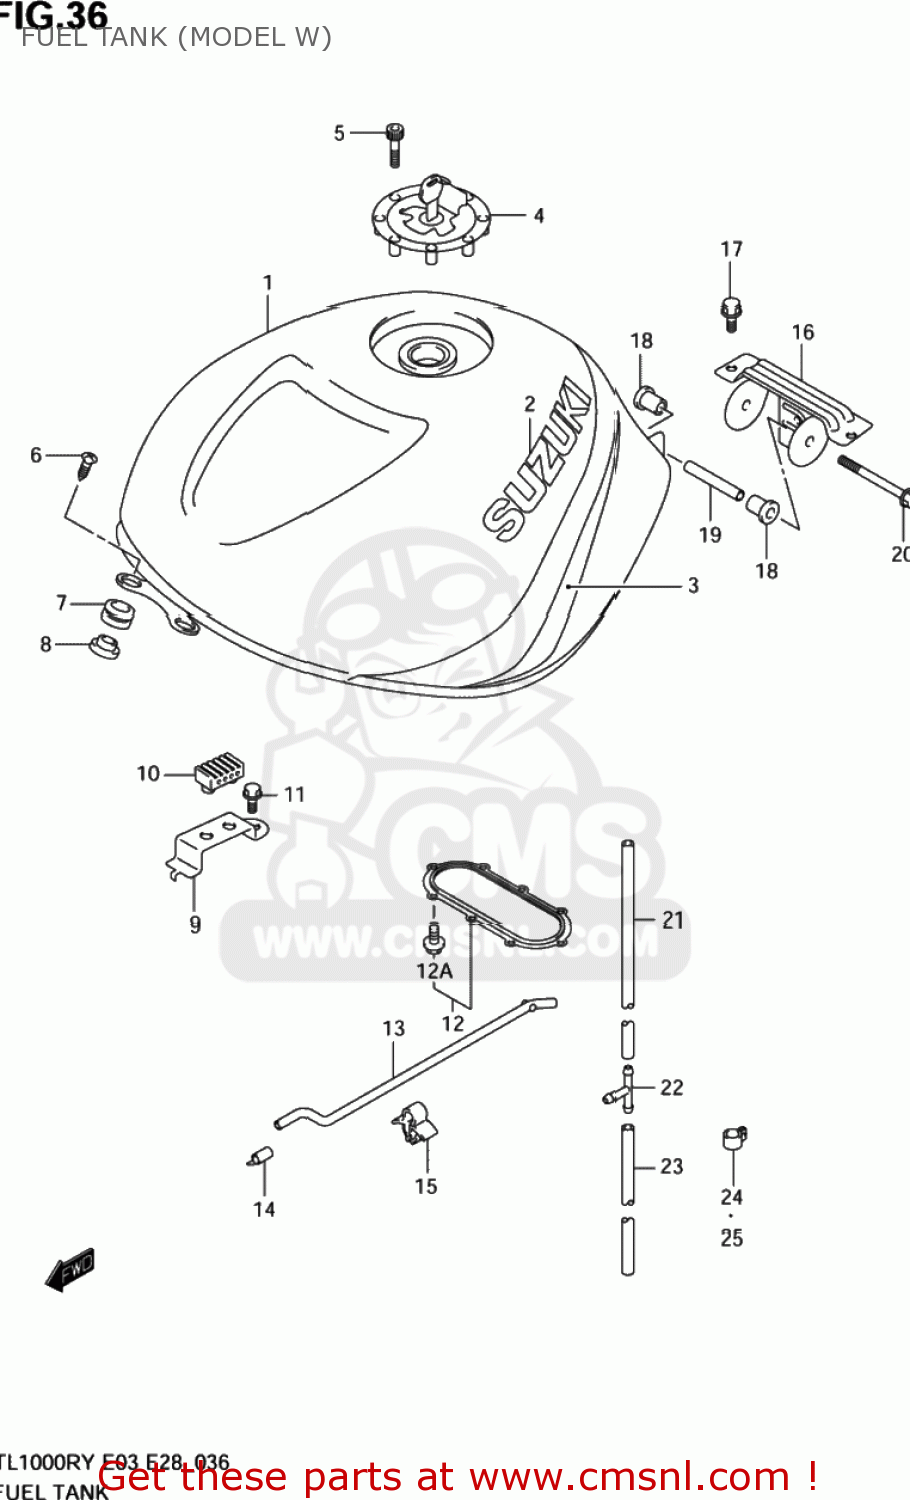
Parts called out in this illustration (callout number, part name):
1	TANK ASSEMBLY,FUEL
2	EMBLEM,FUEL TANK
3	TAPE SET,FUEL TANK(BLUE)
4	CAP SET,FUEL TANK
5	BOLT(5X20)
6	SCREW(6X25)
7	CUSHION
8	WASHER
9	BRACKET,FUEL TANK SIDE CUSHION
10	CUSHION,SEAT(40X20X15)
11	BOLT
12	PACKING SET,FUEL PUMP (NAS)
12A	BOLT,FUEL PUMP
13	STAY,FUEL TANK
14	CAP,OD:11
15	CLAMP
16	BRACKET,FUEL TANK RR
17	BOLT
18	CUSHION,FUEL TANK RR
19	SPACER,FUEL TANK RR
20	BOLT
21	HOSE,FUEL TANK DRAIN
22	3 WAY
23	HOSE(7X10.2X600)
24	CLAMP
25	CLAMP
